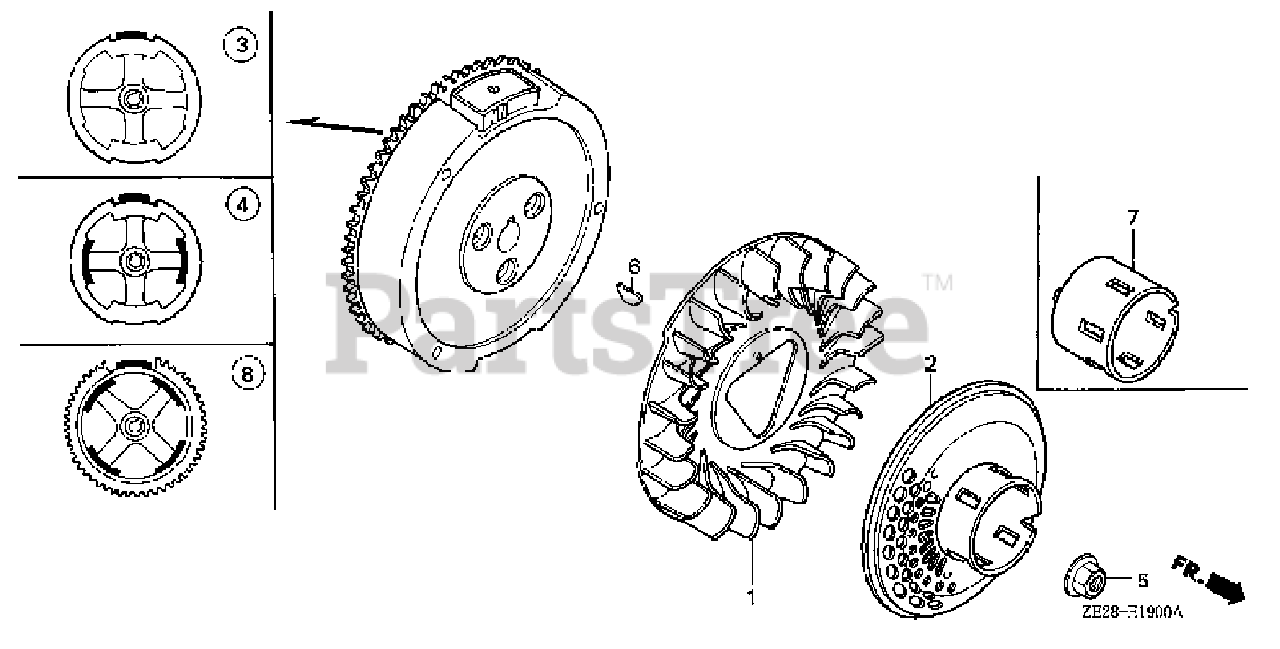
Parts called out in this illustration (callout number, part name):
1	FAN, COOLING
5	NUT, SPECIAL (16MM) (1)
5	NUT, SPECIAL (16MM)
6	KEY, SPECIAL WOODRUFF (25X18)
7	PULLEY, STARTER
8	FLYWHEEL (4POLE)
